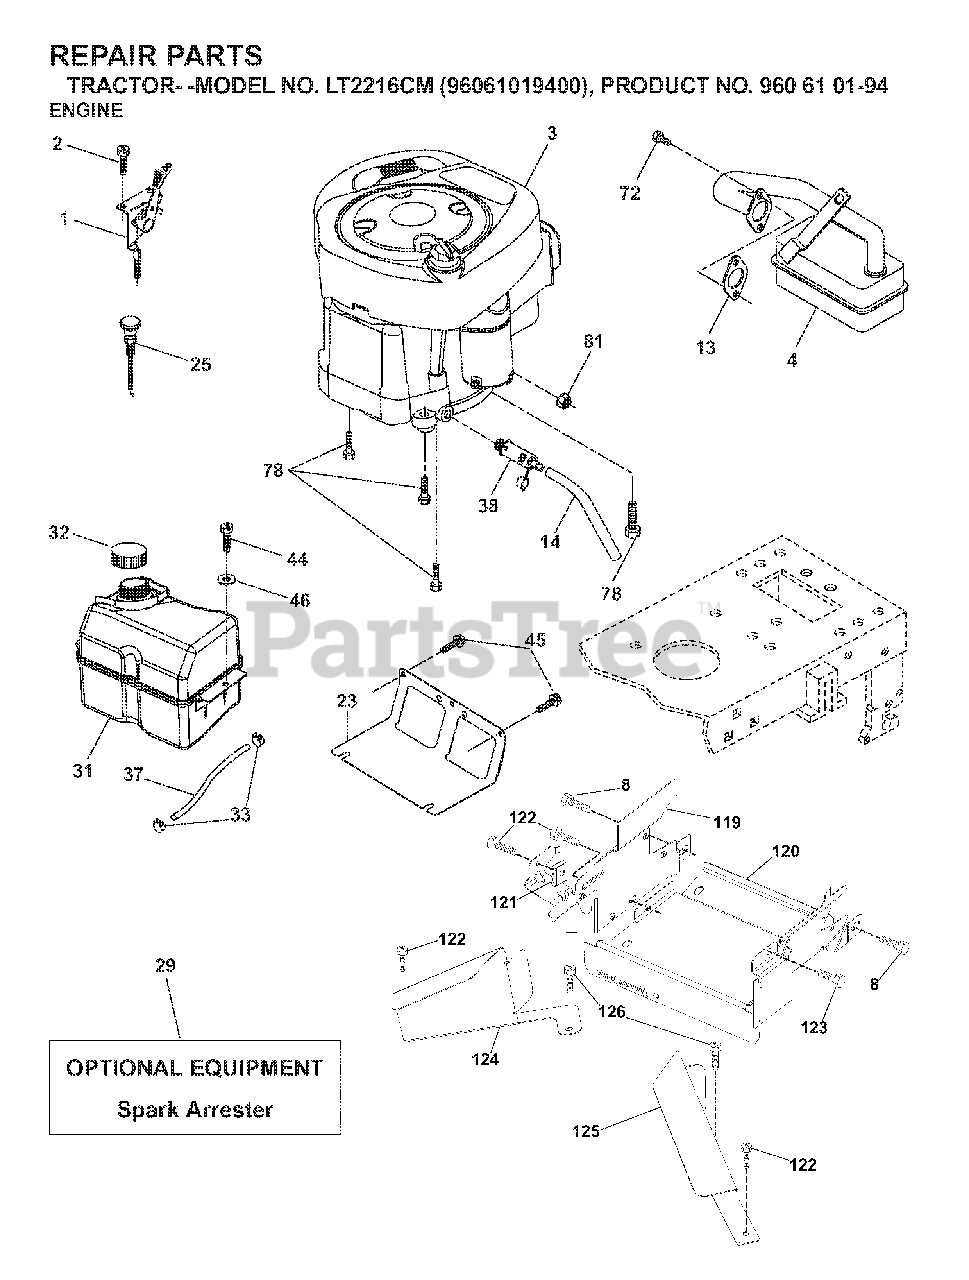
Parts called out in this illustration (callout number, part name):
1	CONTROL TH/CH FLAG
2	SCREW
8	BOLT, 5/16-18 X 1 3/4
13	REPL BY 532 27 22-93
14	TUBE, DRAIN OIL ASM.
23	SHEILD.BROWNING.DBR.GUARD
29	ARRESTER SPARK (OPTIONAL)
31	TANK FUEL
32	FUEL CAP
33	HOSE CLAMP
37	LINE.FUEL.20
38	PLUG DRAIN OIL EASY
44	SCREW HEXWSHR 1/4-20X3/4
45	SCREW, 3/8-16X3/4
72	SCREW.SOCKET HD.5/16-1
78	SCREW.3/8-16
81	NUT
122	SCREW.1/4-20X5/8
123	SCREW, 5/16-18 X 1/2
